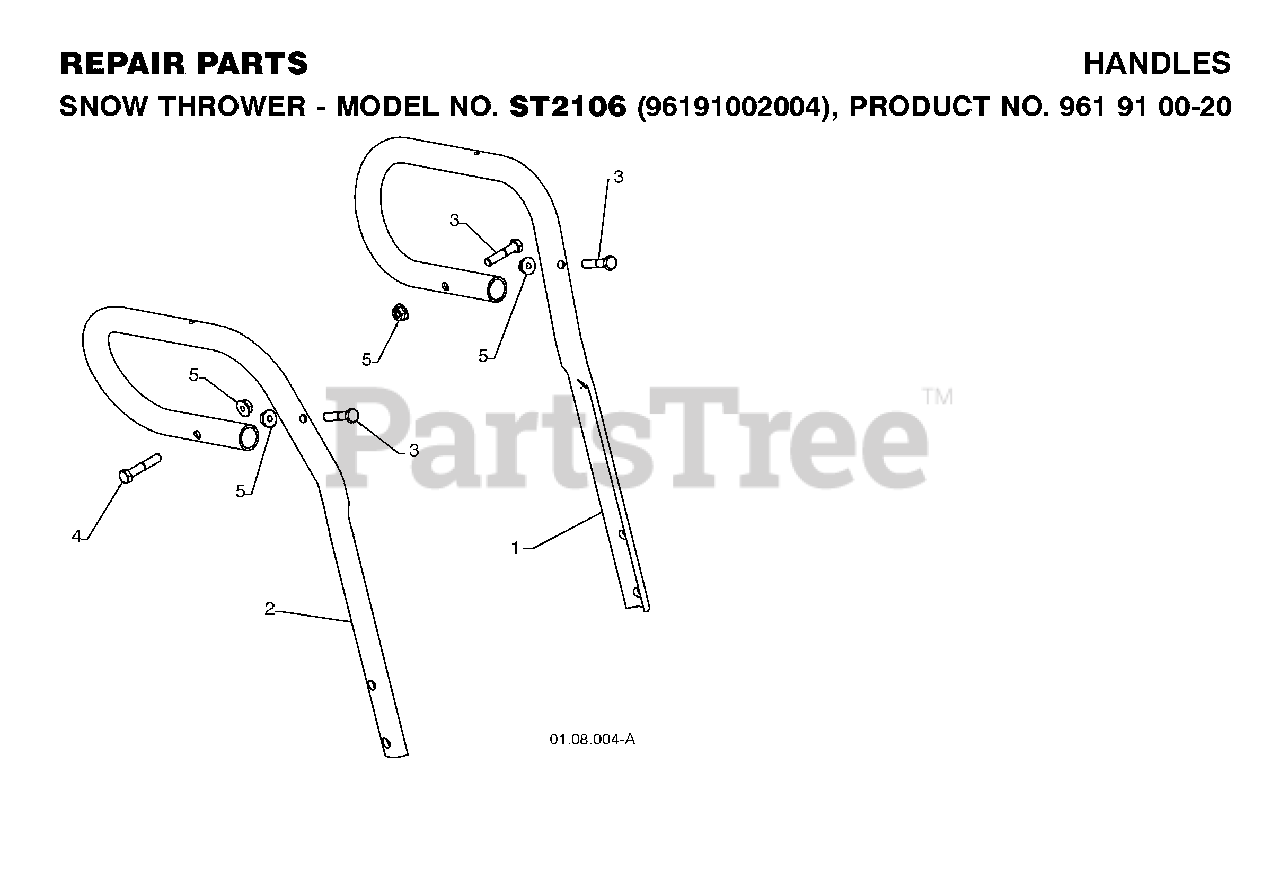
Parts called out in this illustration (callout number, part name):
2	TUBE.HANDLE.LOOP.RH.BLACK
3	HEX BOLT
5	NUT, LOCK 5/16-18
